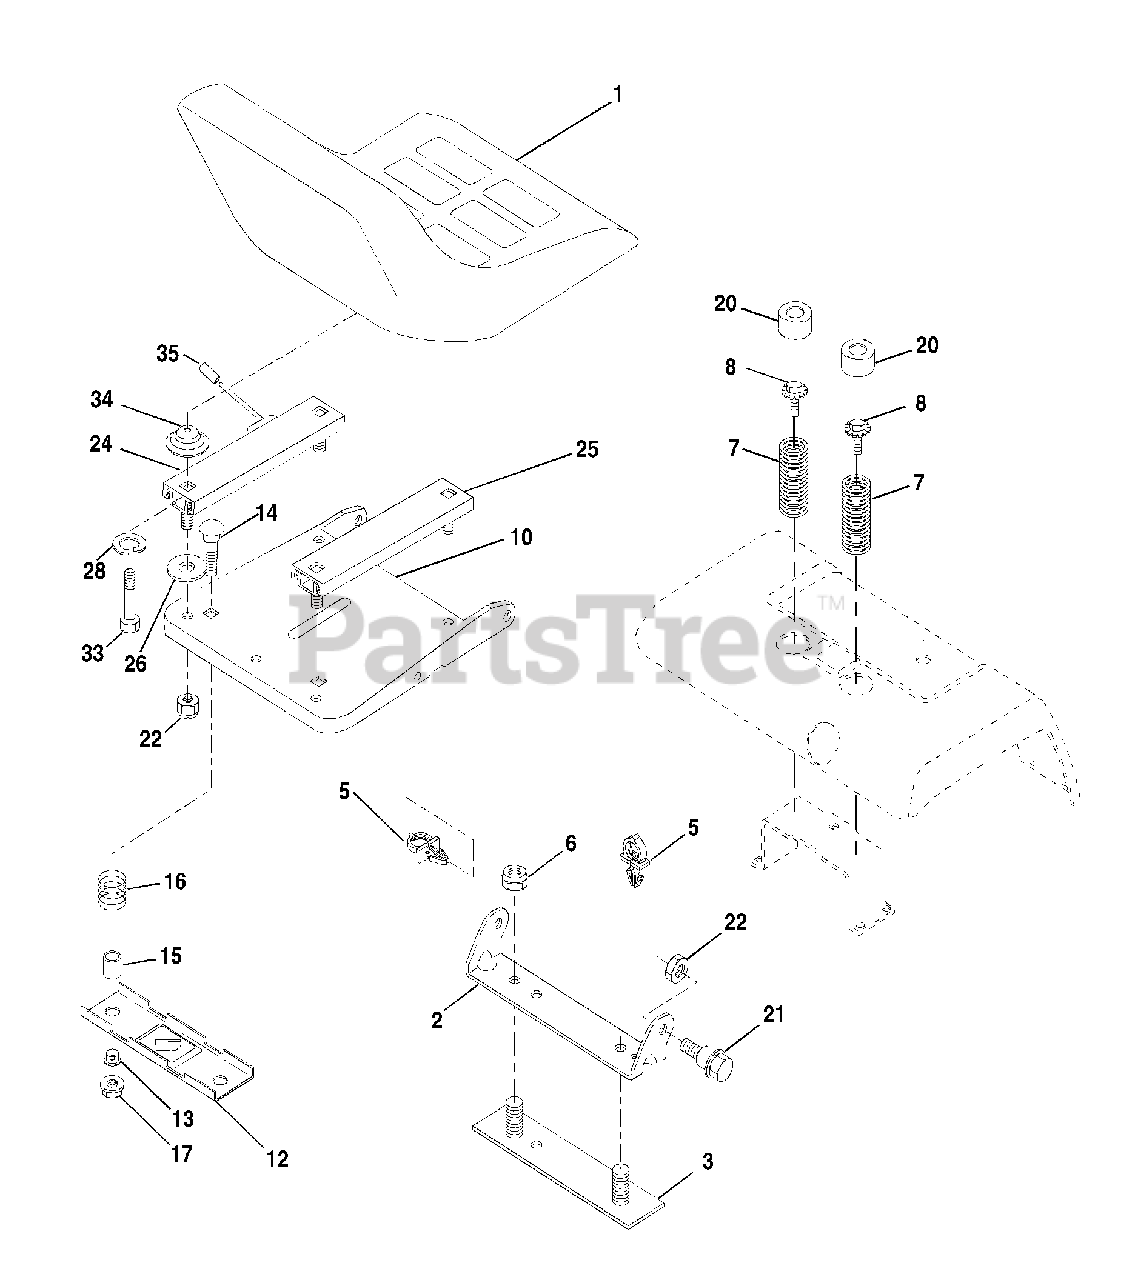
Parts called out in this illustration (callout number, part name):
1	Seat
2	Bracket, Pivot Seat
3	Strap, Fender
5	Clip, Push In Hinged
6	Nut, Crownlock 3/8-16
7	Spring, Seat Cprsn
8	Bolt 5/16-18 UNC X 3/4
10	Pan, Seat
12	Bracket, Mounting Switch
13	Bushing, Snap
14	Bolt, Carriage 1/4-20 X 1-1/2
15	Spacer, Split
16	Spring, Cprsn
17	Nut, Lock 1/4 Lge Flg Gr. 5
20	Cap, Spring Seat
21	Bolt, Shoulder 5/16-18
22	Nut, Crownlock 5/16-18
24	Track Slide Seat LH Locking
25	Track Slide Seat RH Free
26	Washer 11/32 x 5/8 x 12 Ga.
28	Washer Split
33	Bolt Fin Hex 5/16-18 x 1
35	Cap Vinyl
